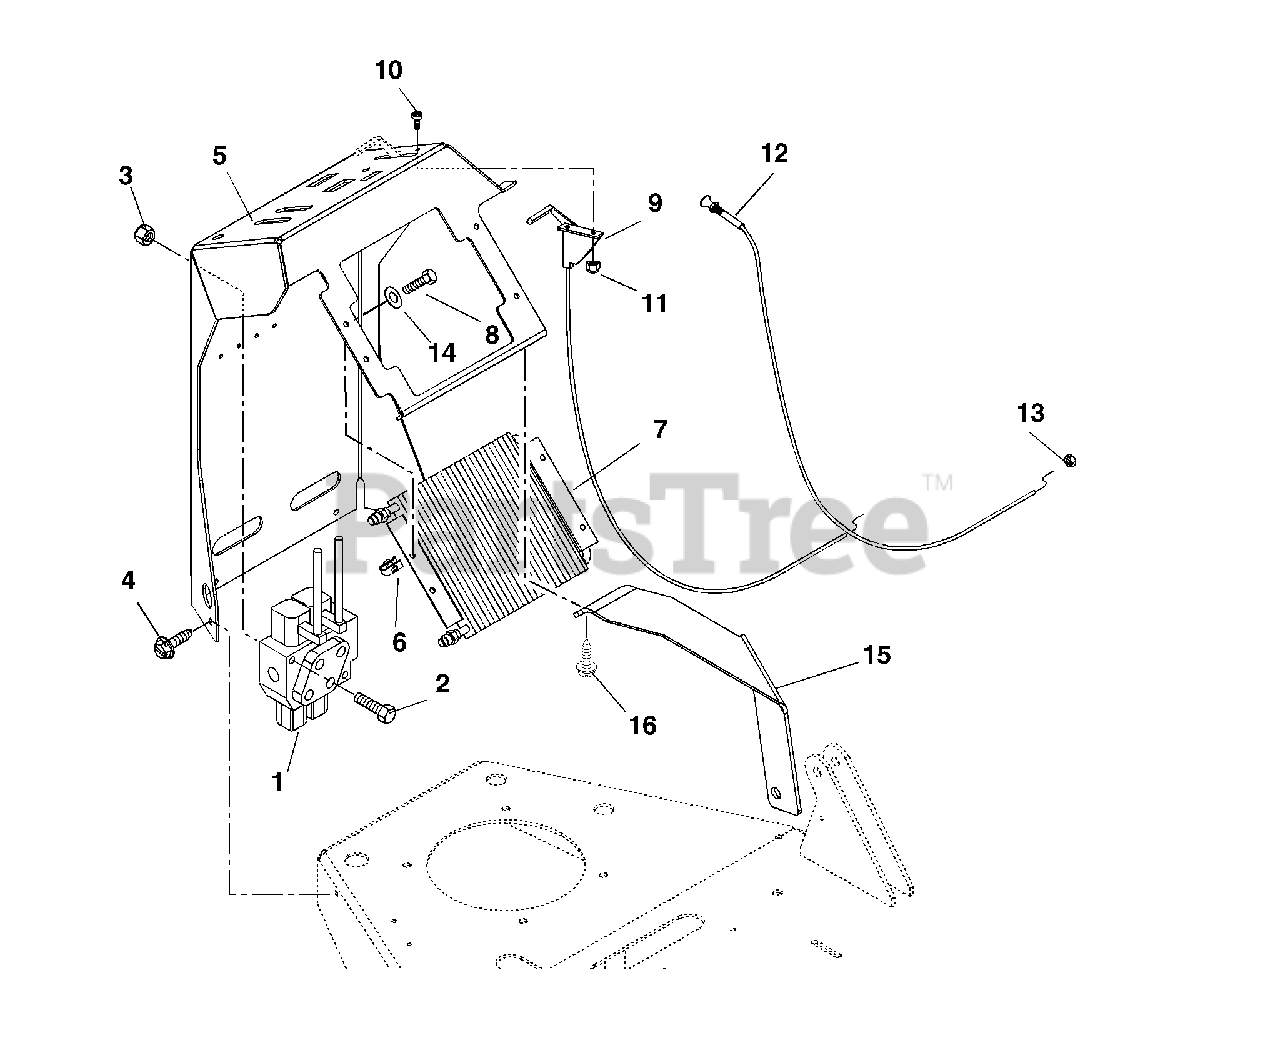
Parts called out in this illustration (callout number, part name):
1	Valve, 2 Spool
2	Bolt-Hex .31-18 x 1.75 Grade 5
3	Nut-Locking-Nylon .31-18
4	Screw-Tapping .38-16 x .75 Hex Washer Head
5	Panel, Control
6	Nut-Retainer .25-20 x .56
7	Cooler, Oil
8	Bolt-Hex .25-20 x .75 Grade 5
9	Cable, Throttle
10	Screw-Machine 10-24 x .50 Hex Washer Head
11	Nut-Locking-Nylon 10-24 with Insert
12	Cable, Choke
13	Nut-Jam .38-24
14	Washer-Flat-Steel .28 x .62 x .065
15	Brace, Instrument Panel-Left Hand
16	Screw-Tapping .25-20 x .50 Hex Washer Head
